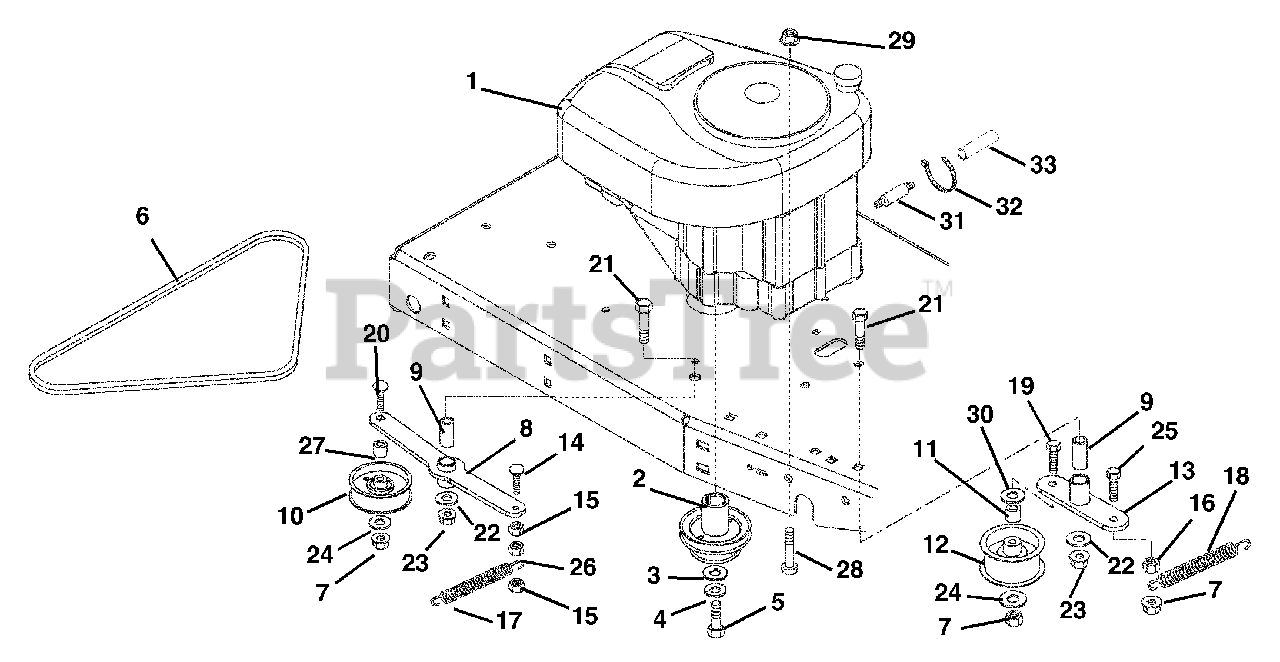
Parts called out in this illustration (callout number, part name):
1	ENGINE GROUP-12 HP
2	ENGINE-SHEAVE
3	WSHR-FL-STL.511X1.441X.125 YWZ
4	@WSHR-LK .44X.109 REG YWZC
5	BLT-HEX .44-20X1.50 GR5 YWZC
6	V-BELT, HA-RAW EDGE
7	NUT-LK-TOP-FLG .38-16 BLKZC
8	WLDM'T-IDLER (IZT)
9	BSHG-SLV .500X.750X1.560
10	IDLER-PLY FLAT 3.25 X .38 X1.0
11	BSHG-SPCR .41X75X.69
12	IDLER 2.75X1.25
13	BRKT, IDLER (WLDMNT)
14	@BLT-RDHDSQNK .31-18X1.25 G5YZ
15	NUT-LK ESNA THIN .50-13 YWZC
16	@NUT-SPNLK-FLG .375-16 YWZC
17	SG-TENS .075X.75X2.25 WLD20.7
18	SG-TENS .080X.687X5.16 WLD 28
19	@BLT-HEX .38-16X2.75 GR5 YWZC
20	@BLT-RDHDSQNK .38-16X2.00 G5YZ
21	@BLT-HEX .50-13X2.25 GR5 YWZC
22	@WSHR-FL-STL.563X1.38X.109YWZC
23	@NUT-LK-TOP-FLG .50-13 YWZC
24	@WSHR-FL-STL.438X1.00X.083 YWZ
25	@BLT-HEX .38-16X1.25 GR5 YWZC
26	@NUT-SPNLK-FLG .312-18 YWZC
27	BSHG-SLV .391X.688X.52 PM
28	SCR-SKH BTHD .31-18 X 1.50 GR8
29	@NUT-LK-TOP-FLG .31-18 YWZC
30	WSHR,FLT .438X1.00X.160 ZCC
31	VALVE, OIL DRAIN
32	CABLE TIE LG 5-1/2
33	TUBE, OIL DRAIN 8" CLEAR VINYL
